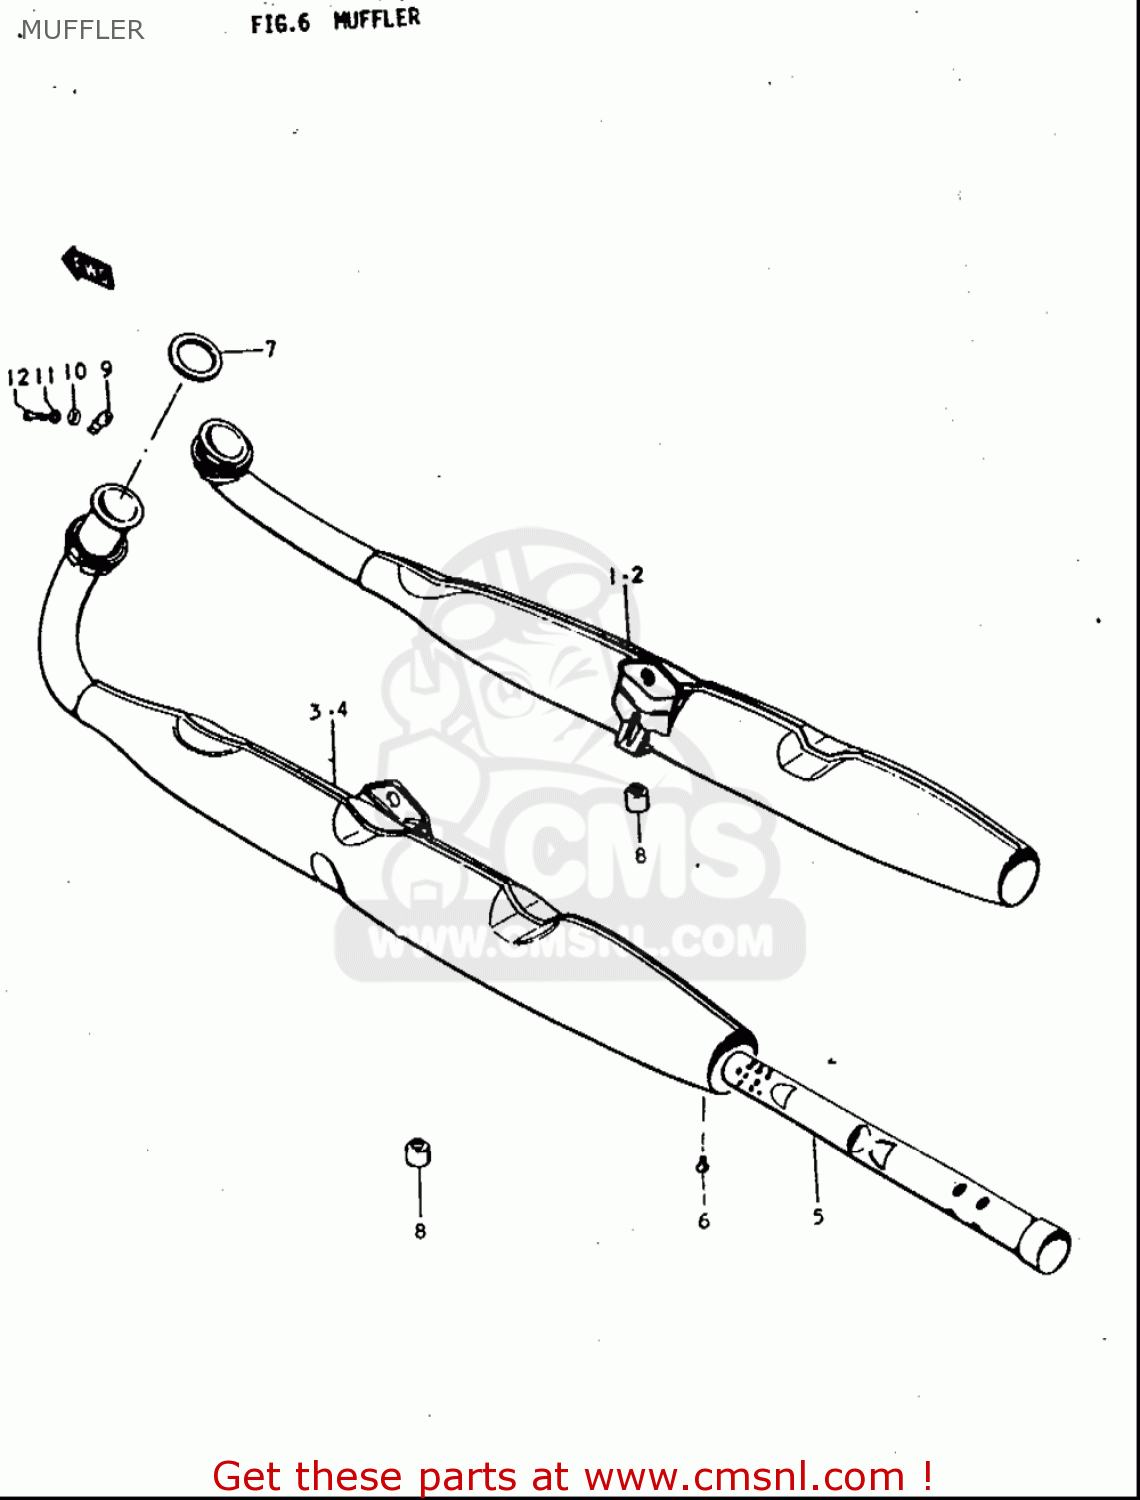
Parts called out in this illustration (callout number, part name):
6	SCREW(5X6)
7	GASKET,EXHAUST PIPE (NAS)
8	CUSHION
9	PLATE,EXHAUST PIPE
10	WASHER
11	WASHER,LOCK
12	SCREW
